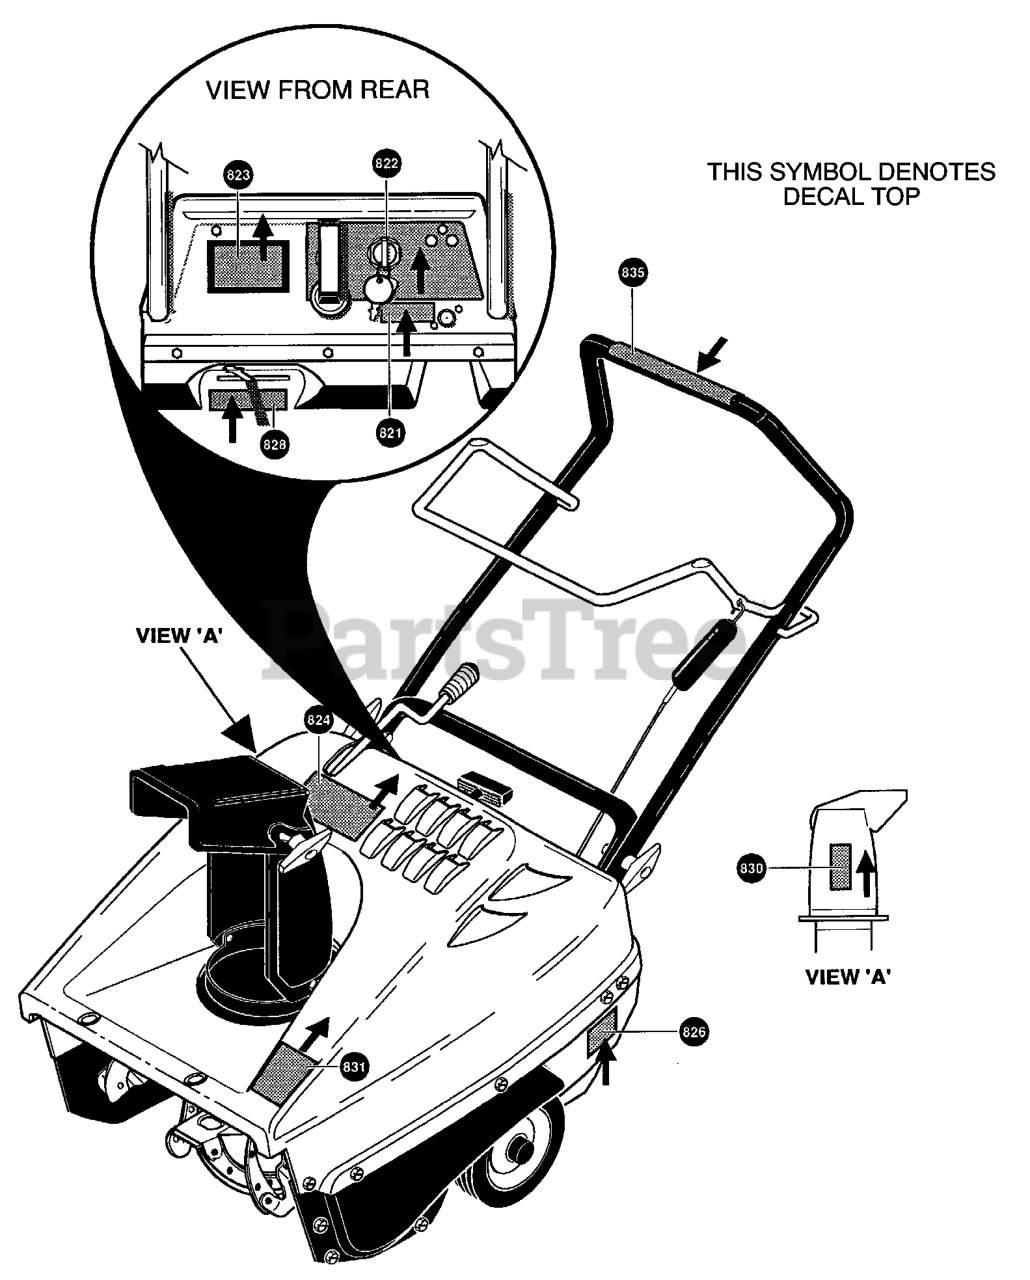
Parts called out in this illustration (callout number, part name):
820	DECAL, EPA 5HP, MASS
821	DECAL, ELECTRIC START FRE/ENG
822	DECAL, DASH
823	DECAL, SPARK PLUG ACCESS
824	DECAL, SNOW MAX
826	DECAL, MUFFLER HOT
828	DECAL, OFF-CHOKE-ON
830	DECAL, DANGER CHUTE -HAND
831	DECAL, DANGER AUGER -FOOT
835	DECAL, AUGER CONTROL BAR
